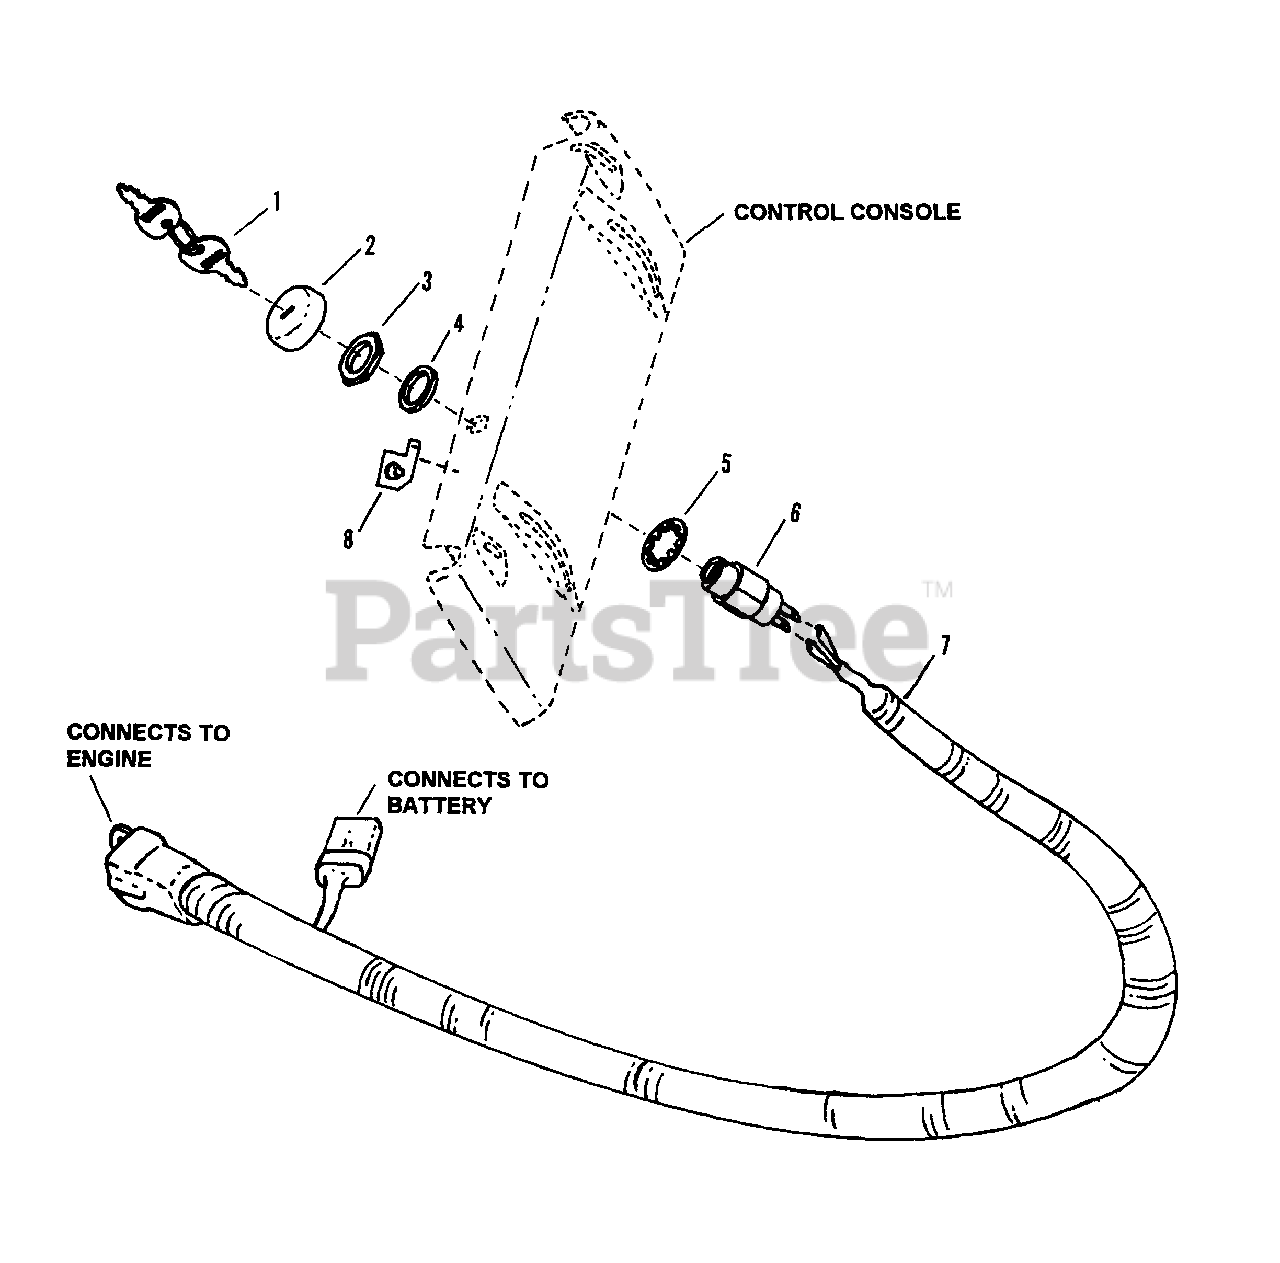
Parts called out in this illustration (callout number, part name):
1	KEY, Ignition
2	BEZEL
3	NUT, 5/8-32 Hex
4	SPACER, 21/32" x 7/8"
5	WASHER, 5/8" Internal Tooth Lock
6	SWITCH, Electric Start
7	HARNESS, Wiring L Series
8	DECAL, Key/Start
